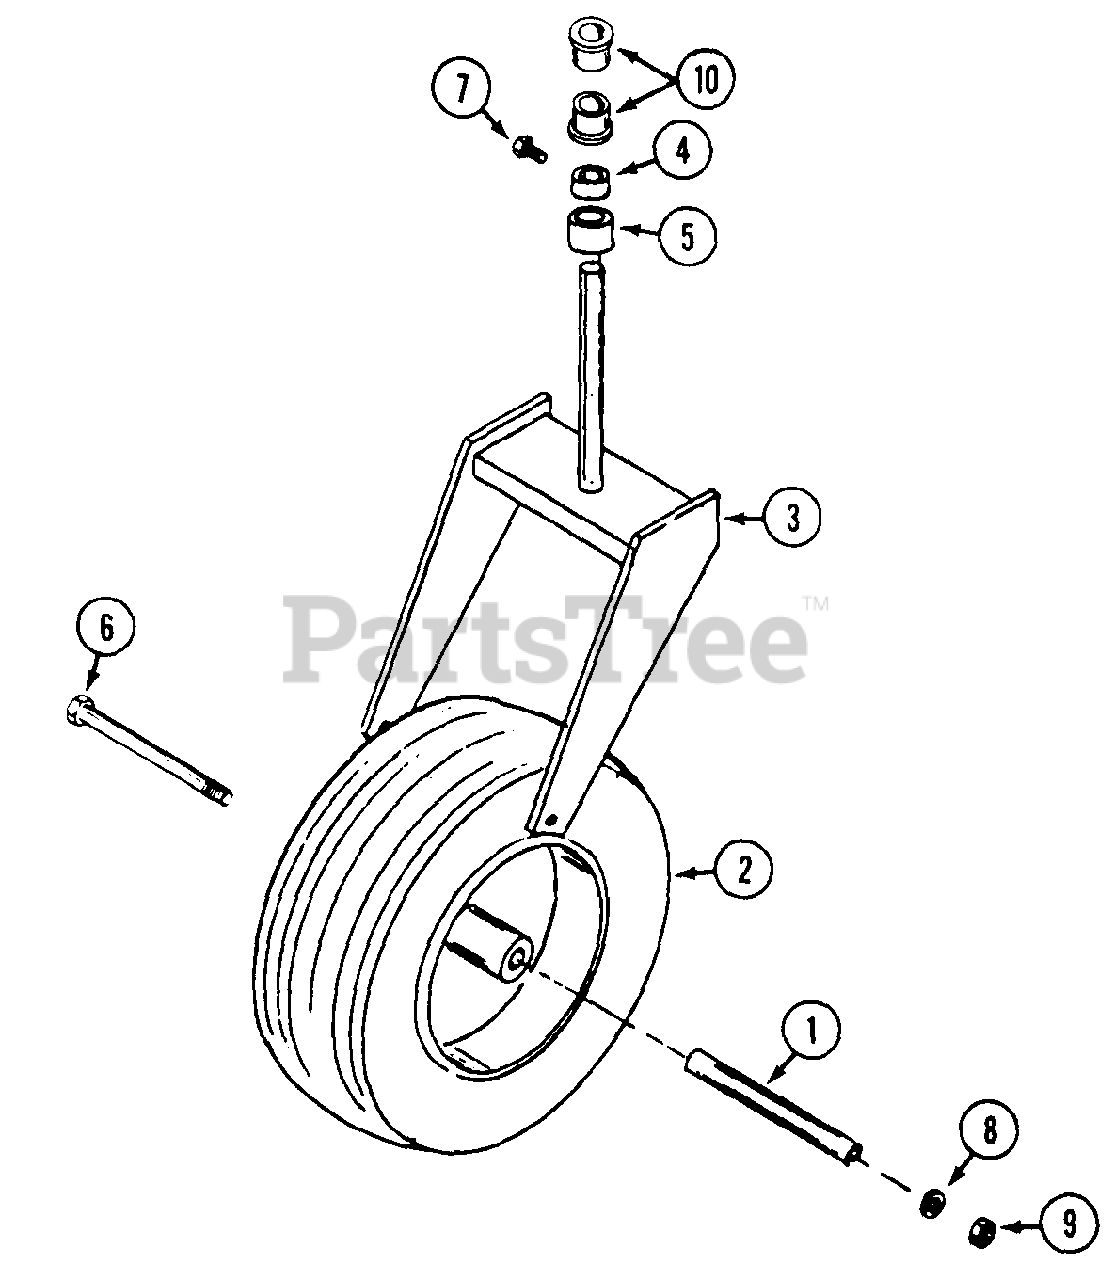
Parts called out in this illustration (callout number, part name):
2	WHEEL ASSEMBLY - tail
3	FORK - tail wheel
4	COLLAR - set 1"
5	SPACER - tail wheel fork
6	BOLT - 1/2"-13 x 9-1/2"
7	SCREW - set 5/16"-18 x 1/2" square head
8	LOCKWASHER - 1/2"
9	NUT - 1/2"-13
10	BEARING - ball 1"
